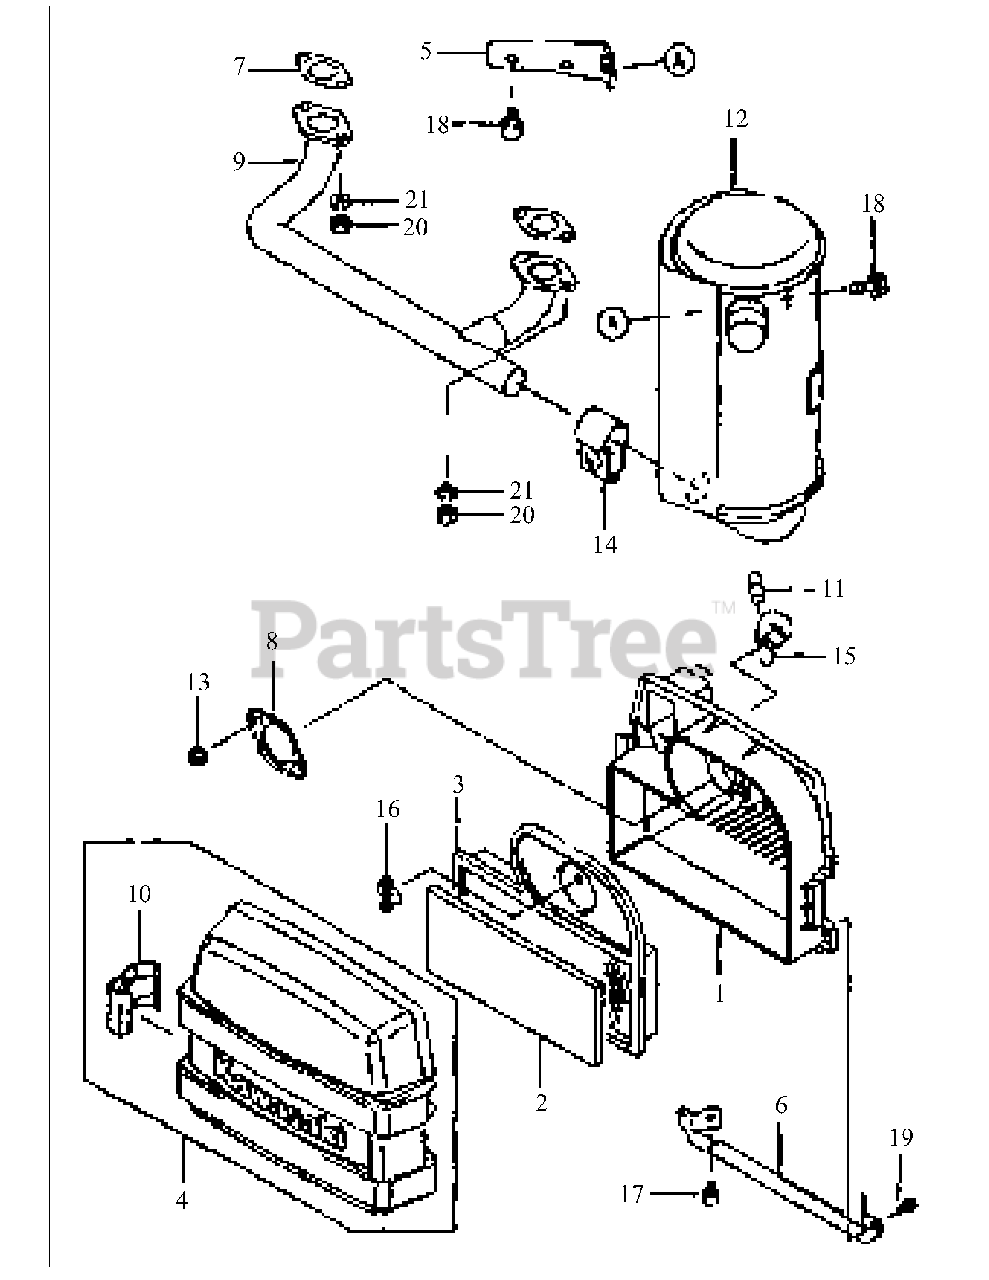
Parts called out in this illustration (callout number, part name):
1	Case, Air Filter
2	Element, Pre Filter
3	Element, Air Filter
4	Case, Air Filter
7	Gasket, Muffler
9	Pipe, Exhaust
10	Hook, Air Filter
17	Bolt, Flange
18	Bolt, Flange
19	Screw
21	Washer, Spring
